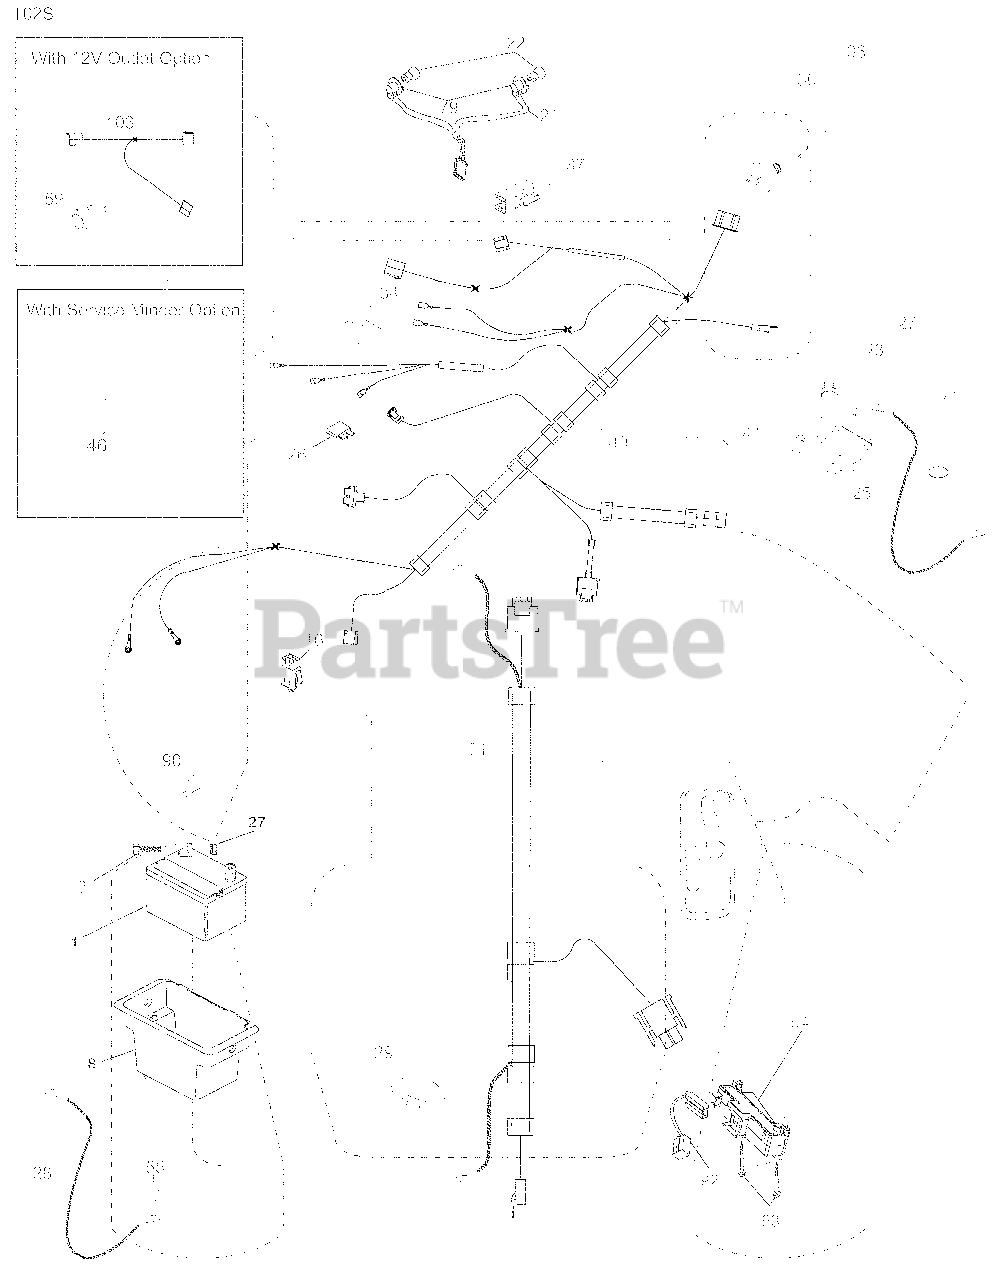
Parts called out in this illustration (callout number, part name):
1	Battery
2	Bolt Hex Head 1/4-20 x 3/4
8	Box Battery
16	Switch Interlock Push-In
21	Harness Socket Light W/4152J
22	Bulb Light
25	Cable Starter
27	Nut Keps Hex 1/4-20 unc
28	Cable, Ground
29	Switch, Seat
30	Switch, Ign
34	Switch Light / Reset
40	Harness Ign. Dash
41	Screw Thd Cut 1/4-20 x 1/2
42	Cover, Terminal
43	Solenoid
55	Screw Thdrol 5/16-18 x 3/4
71	Harness Chassis
79	Socket Asm Bulb Twistlock
87	Switch Interlock Clutch Cable
90	Cover, Terminal Battery
92	Harness Pigtail Reverse Switch
93	Screw Plastite 10-14 x 2.0
94	Module Reverse ROS
